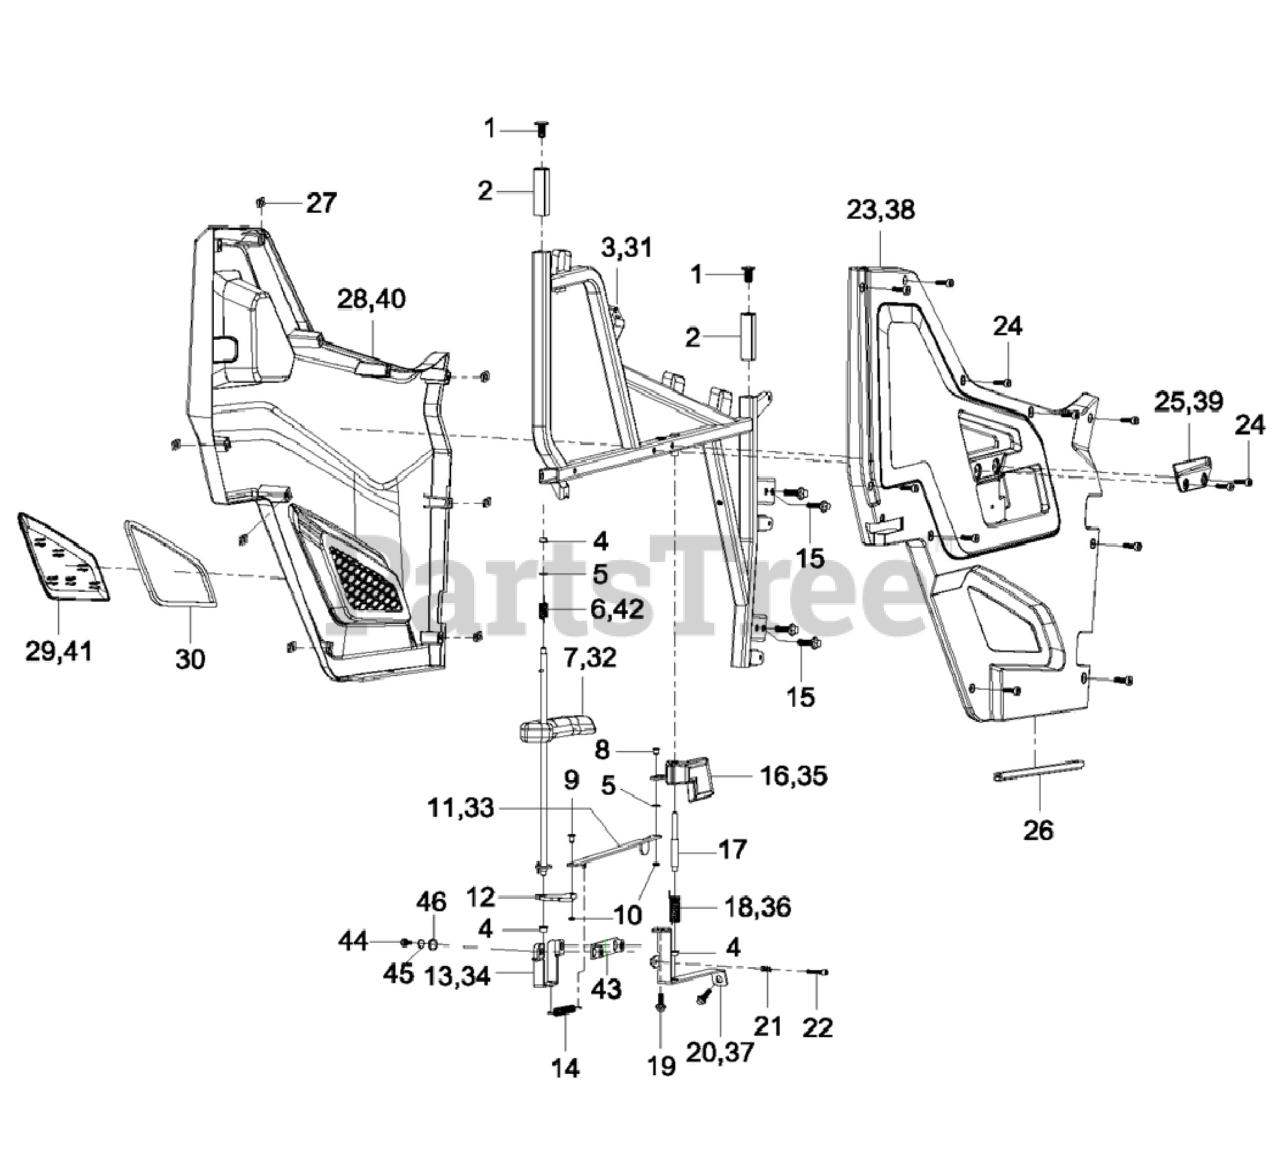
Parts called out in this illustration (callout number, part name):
1	PLUG - DOOR
2	UPPER DOOR SEAT
3	DOOR FRAME - LEFT LOWER
4	BUSHING PLASTIC 8x11
6	SPRING RETURN AL
7	OUTSIDE DOOR HANDLE KIT - LEFT
8	PIN - SHOULDER 8x11
9	PIN - SHOULDER 8x14
10	CLIP
11	DOOR LOCK ROD - LEFT
12	DORR LOCK KIT
13	INSIDE DOOR LOCK LEVER SEAT - LEFT
14	SPRING PULL S
15	Flange bolt M8x25
16	INSIDE DOOR HANDLE KIT - LEFT
17	PIN - SHOULDER 8x104-12x47
18	SPRING - TORSION AJ
19	Hexagon Flange Bolt M6x16
20	INSIDE DOOR LOCK LEVER SEAT - LEFT
21	PRESSURE SPRING M
22	HExAGON SOCKET HEAD CAP SCREWS M6x40
23	DOOR PROTECTOR - LEFT INSIDE?
24	Socket Hex Flat Head Bolt M6x16
25	DOOR PULL - LEFT
26	DOOR STRIPS
27	CLAMP NUT M6x6
28	DOOR PROTECTOR - LEFT OUTSIDE?
29	COVER DOOR BREATHER WINDOWS - LEFT
29	COVER DOOR BREATHER WINDOWS LEFT YELLOW
29	COVER DOOR BREATHER WINDOWS LEFT BLUE
29	COVER DOOR BREATHER WINDOWS LEFT BLACK
29	COVER DOOR BREATHER WINDOWS LEFT CAMO
31	DOOR FRAME- RIGHT KIT
32	OUTSIDE DOOR HANDLE KIT - RIGHT
33	DOOR LOCK ROD - RIGHT
34	INSIDE DOOR LOCK LEVER SEAT - RIGHT
35	INSIDE DOOR HANDLE KIT - RIGHT
36	SPRING - TORSION AK
37	INSIDE DOOR LOCK SEAT - RIGHT
38	DOOR PROTECTOR - RIGHT INSIDE?
39	DOOR PULL - RIGHT
40	DOOR PROTECTOR - RIGHT OUTSIDE?
41	COVER DOOR BREATHER WINDOWS RIGHT RED
41	COVER DOOR BREATHER WINDOWS RIGHT YELLOW
41	COVER DOOR BREATHER WINDOWS RIGHT BLUE
41	COVER DOOR BREATHER WINDOWS RIGHT BLACK
41	COVER DOOR BREATHER WINDOWS RIGHT CAMO
42	SPRING - RETURN AM
43	SEAT MOOUNTING PLATE LOCK
44	Hexagon Flange Bolt M8X20
45	Spring Washer-8
